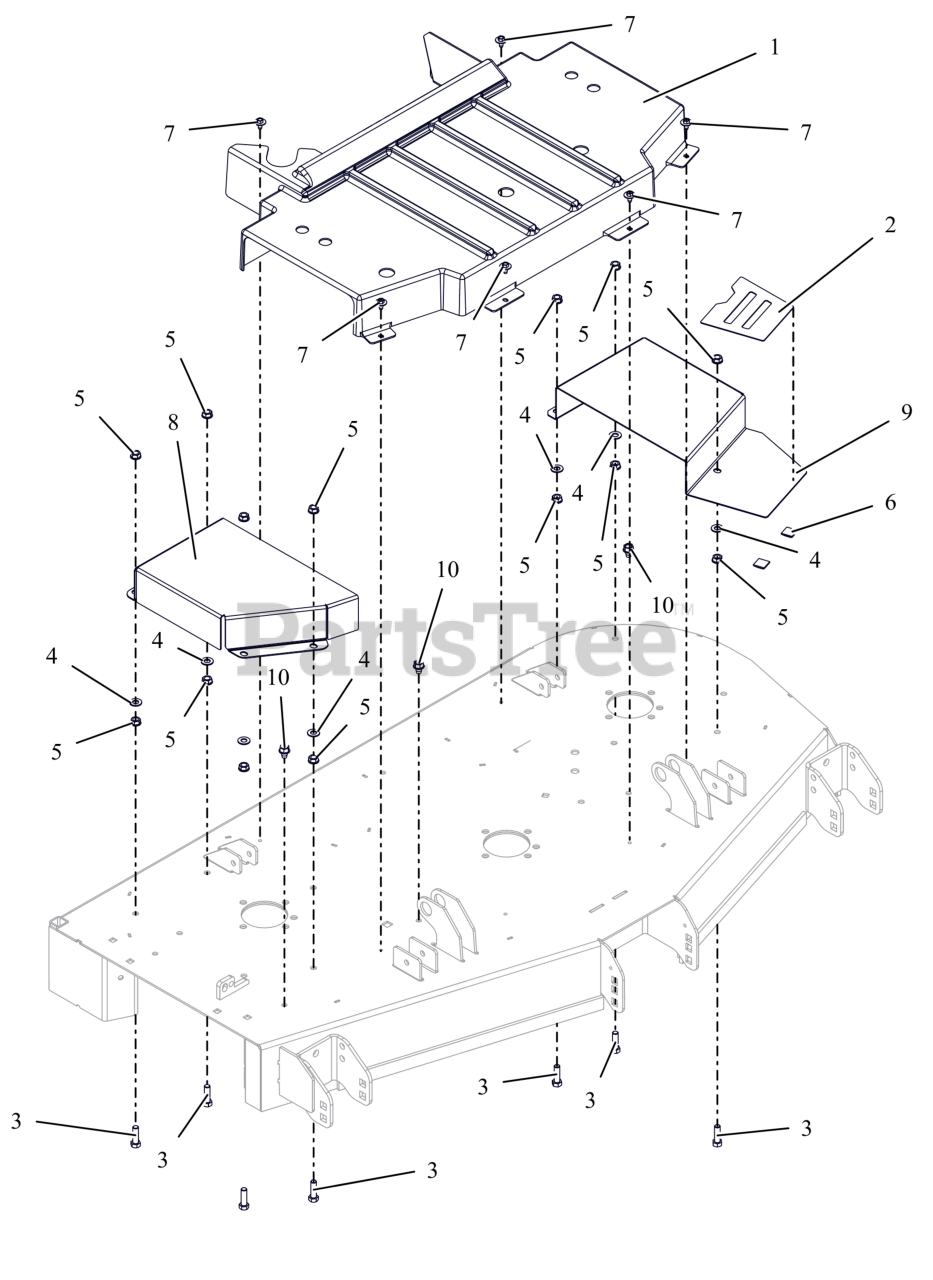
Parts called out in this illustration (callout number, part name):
1	GUARD,CENTER,DECK SPINDLE CE
2	GRIP TAPE 52-60 BELT COVER
3	BLT, HEX .38-16X1.25 G5 ZCC
4	WSHR,FLT .406X.812X.065 ZCC
5	NUT, SPNLK-FLG .38-16 G5 ZCC
7	SCR, TAP .25-20X.50 LG HWH ZCC
8	GUARD,BELT 52" RIGHT CE
9	GUARD,BELT 52" LEFT CE
10	SCR,TAP .375-16X.50 HWH TR ZCC
